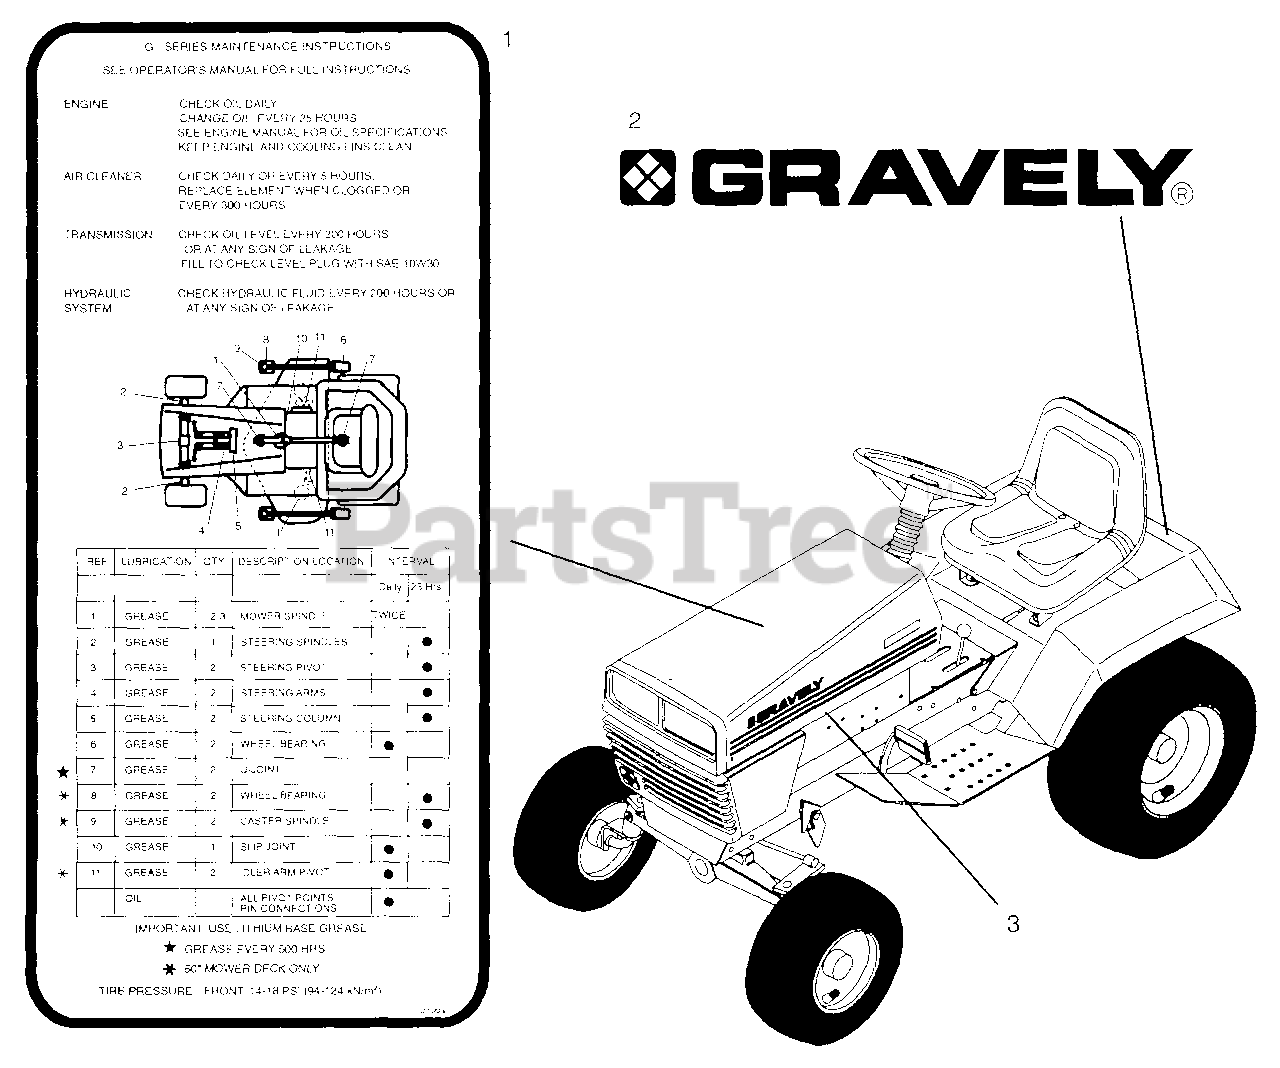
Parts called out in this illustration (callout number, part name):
1	Decal-G-Series Maintenance
2	Decal-GRAVELY Logo
3	Decal-Hood-G Series
